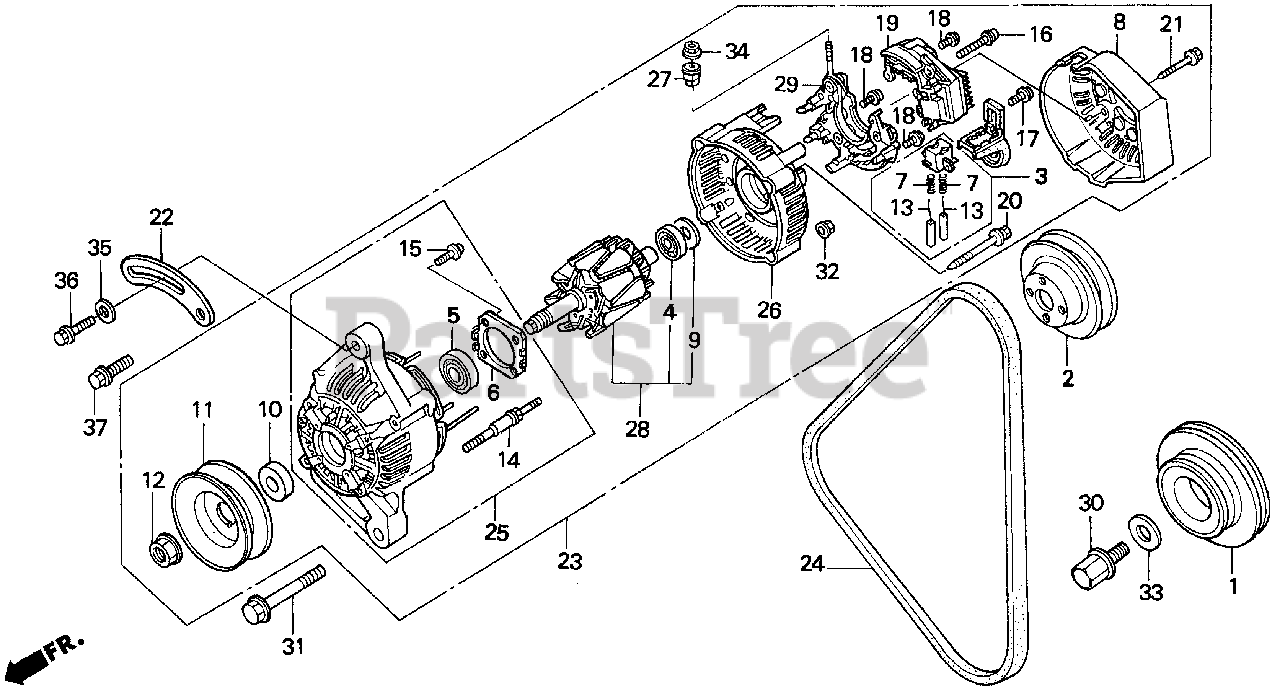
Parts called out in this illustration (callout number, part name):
1	PULLEY, CRANKSHAFT
2	PULLEY, WATER PUMP
3	HOLDER ASSY., ALTERNATOR BRUSH
4	BEARING, RR.
5	BEARING, FR.
6	PLATE, RETAINER
7	SPRING, BRUSH
8	COVER, RR. END
9	COVER, BEARING
10	COLLAR, SPACE
11	PULLEY, ALTERNATOR (NOT AVAILABLE)
12	NUT, PULLEY LOCK
13	BRUSH
14	BOLT, STUD
15	SCREW-WASHER
17	SCREW-WASHER (4X25)
19	REGULATOR ASSY.
20	BOLT-WASHER
22	STAY, ALTERNATOR
23	ALTERNATOR ASSY.
24	BELT, ALTERNATOR (BANDO)
25	FRAME ASSY., DRIVE END
26	FRAME, RR. END
27	BUSH, INSULATION
28	ROTOR ASSY.
29	RECTIFIER ASSY.
30	BOLT, SPECIAL (12MM)
31	BOLT, ALTERNATOR (8X50)
32	NUT, HEX. (5MM)
33	WASHER (12X30X4.5)
34	NUT, HEX. (6MM)
35	WASHER, PLAIN (8MM)
36	BOLT, FLANGE (8X25)
37	BOLT, FLANGE (10X22)
